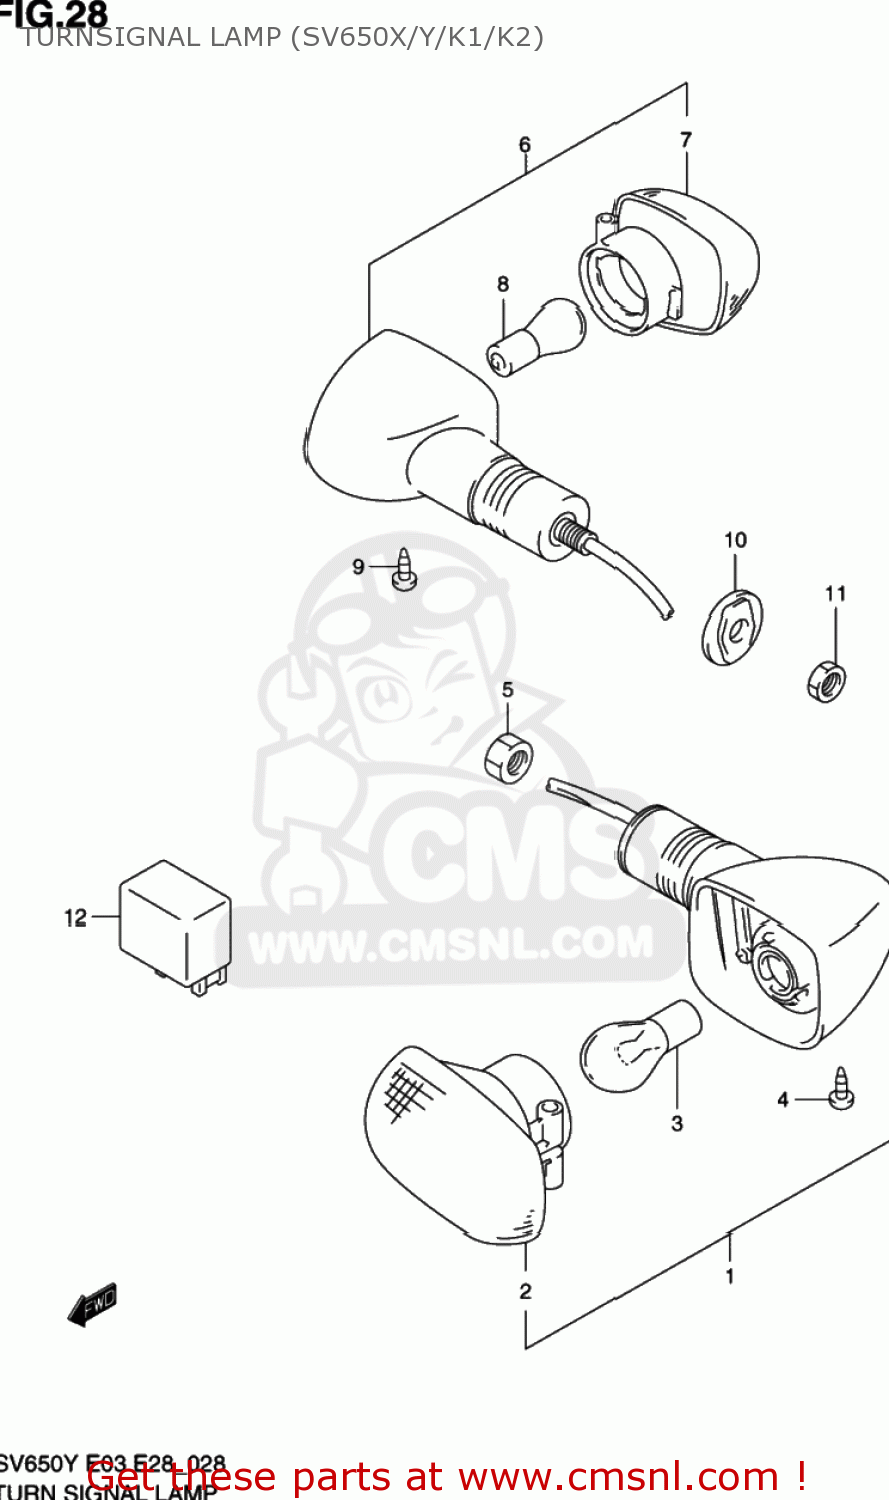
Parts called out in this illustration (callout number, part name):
1	LAMP ASSY,FR TURN SIGNAL,R
2	LAMP UNIT
3	BULB(12V21W)
4	SCREW
5	NUT
6	LAMP ASSEMBLY,REAR TURN SIGNAL
7	LAMP UNIT
8	BULB(12V21W)
9	SCREW
10	SPACER,RR TURNSIGNAL
11	NUT
12	RELAY ASSY,TURNSIGNAL LAMP
